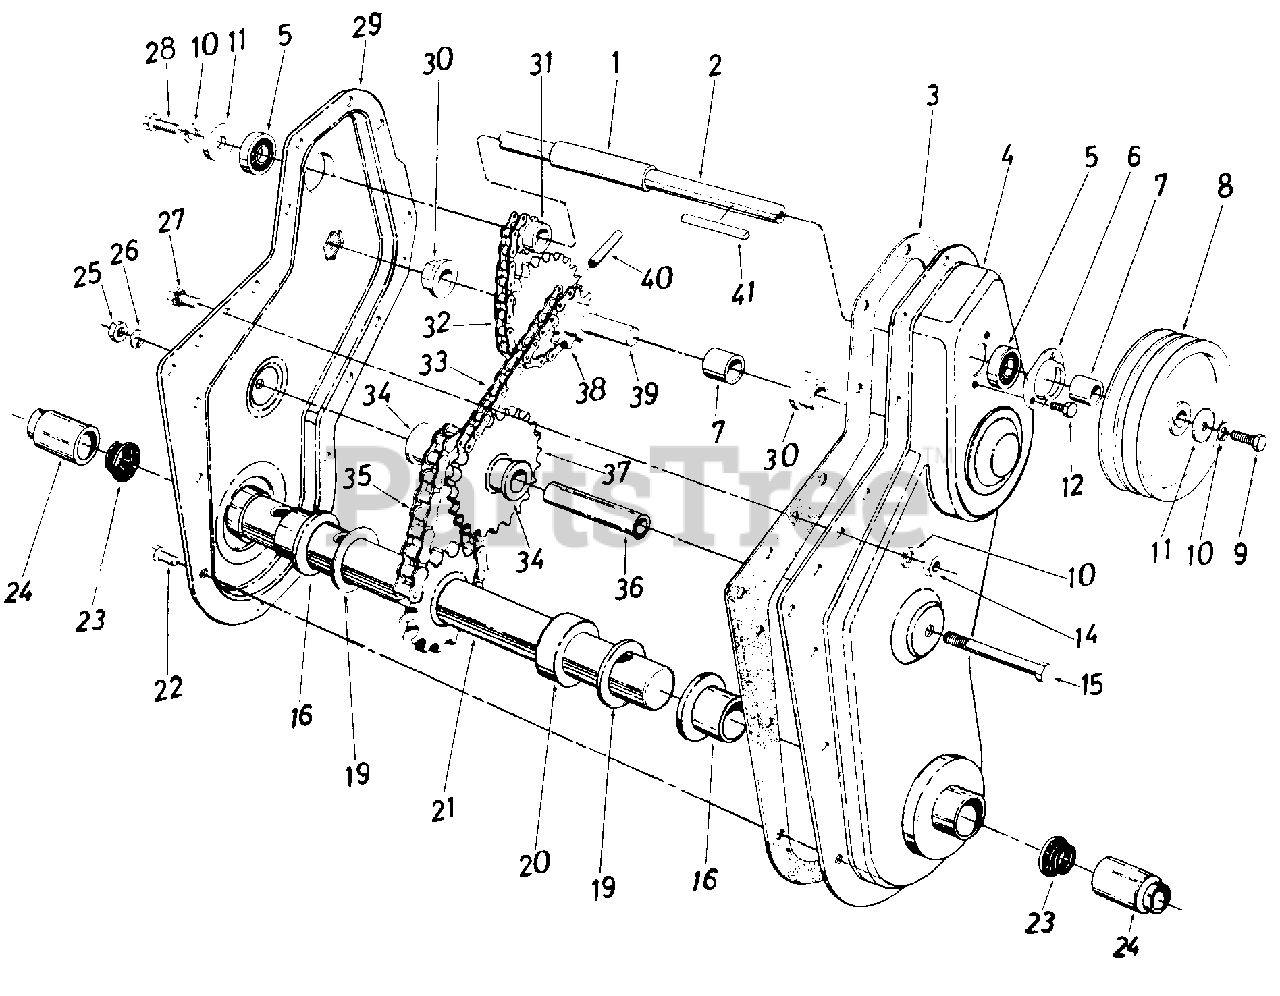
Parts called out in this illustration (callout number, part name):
1	Spacer .657 I.D. x .78 O.D. x 2.19" Lg.
2	Jackshaft
3	Housing Gasket
4	Housing Ass'y.-L.H. Half
5	Ball Bearing .625 I.D. x 1.375 O.D.
6	Bearing Housing
7	Spacer .635 I.D. x .88 O.D. x 1.03" Lg.
8	Chain Case Pulley 6.0" Dia.
9	Hex Bolt 5/16-18 x 1.0" Lg.
10	L-Wash. 5/16" I.D.*
11	Fl-Wash. .344" I.D. x 1.125n O.D.
12	Hex Wash. Hd. Self-Tap Scr. 1/4-20 x .50" Lg.
14	Hex Nut 5/16-18 Thd.
15	Hex Bolt 3/8-16 x 3.25" Lg.
16	Flange Bearing (Plastic)
19	Flat Thrust Wash.
20	Step Spacer
21	Tine Shaft Ass'y.
22	Hex Wash. Hd. Self-Tap Scr. 1/4-20 x .50" Lg.
23	Seal Ring
24	Dust Cap
25	Hex Nut 3/8-16 Thd.
26	L-Wash. 3/8" I.D.
27	Hex Sems Bolt 5/16-18 x 1.00" Lg
28	Hex Bolt 5/16-18 x .62" Lg.
29	Housing Ass'y.-R.H. Half
30	Hex Flanged Bearing
31	Sprocket 10 Teeth 1/2" Pitch
32	#41 Chain 1/2" Pitch x 34 Links
33	#420 Chain 1/2" Pitch x 48 Links
34	Flange Bearing .625" I.D.
35	#50 Chain 5/8" Pitch x 28 Links
36	Sprocket Shaft
37	Sprocket Bearing Sleeve Ass'y.
38	Sprocket Sleeve Ass'y.
39	Sprocket Shaft
40	Spring Pin Spiral 1/4" Dia. x 1.5" Lg.
41	Square Key 3/16 x 3/16 x 1.50" Lg.
